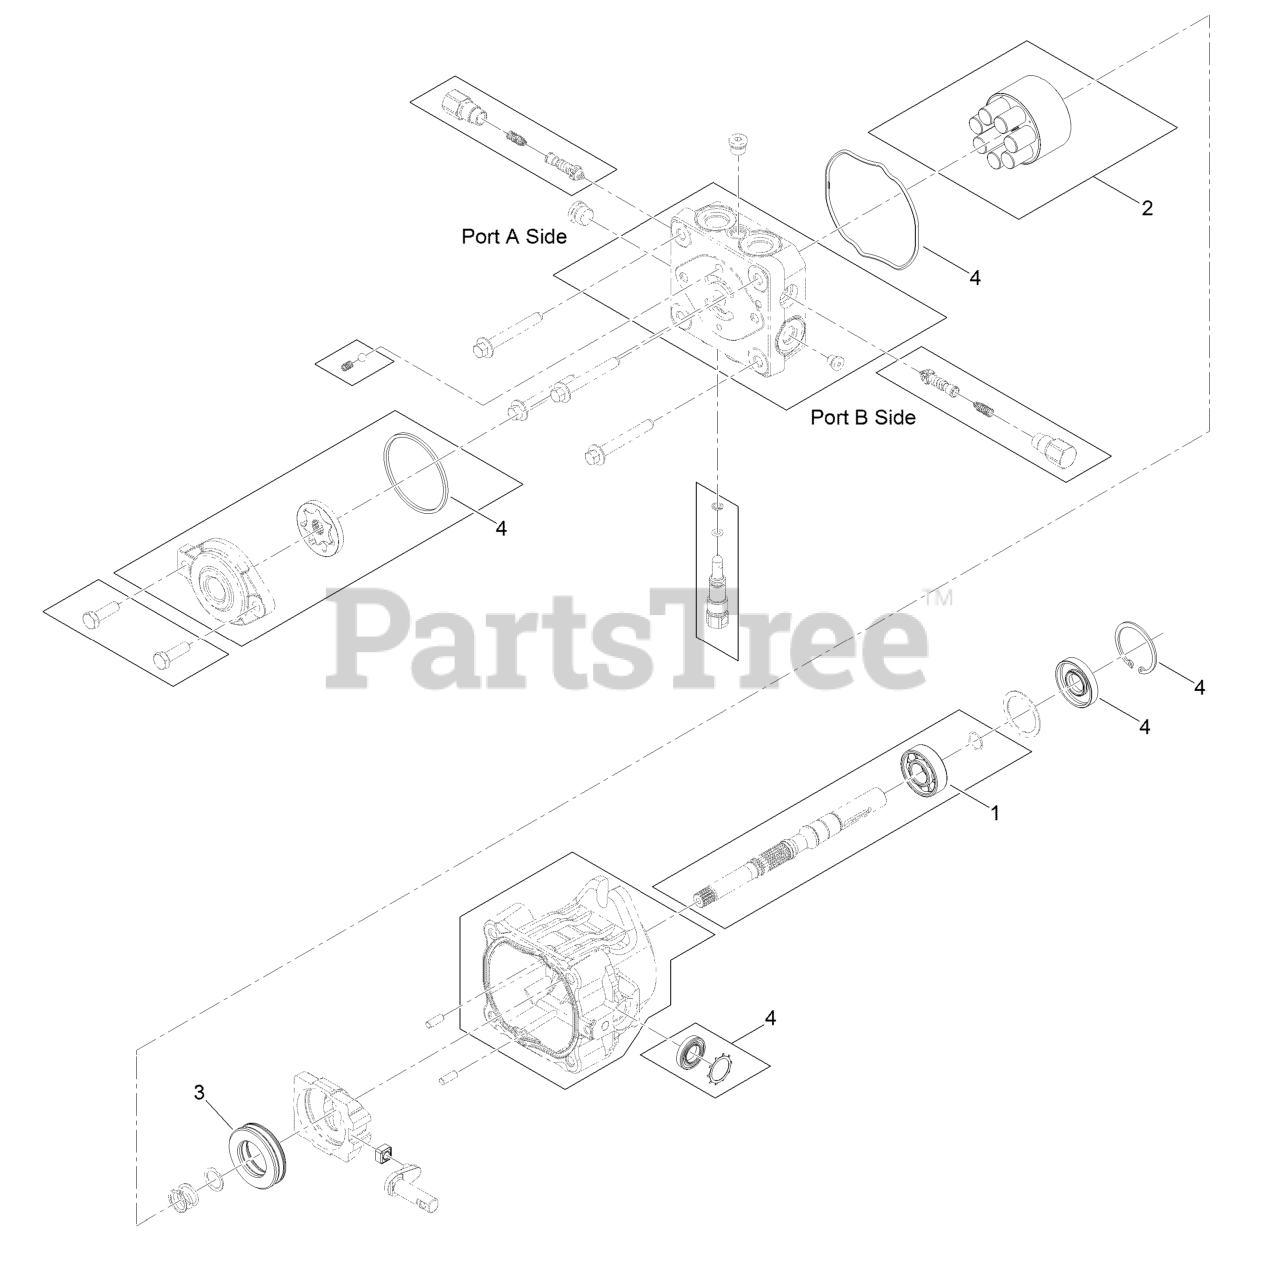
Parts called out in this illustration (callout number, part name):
1	BEARING-BALL
2	CYLINDER BLOCK KIT
3	BEARING-THRUST, PLASTIC C
4	SEAL OVERHAUL KIT
